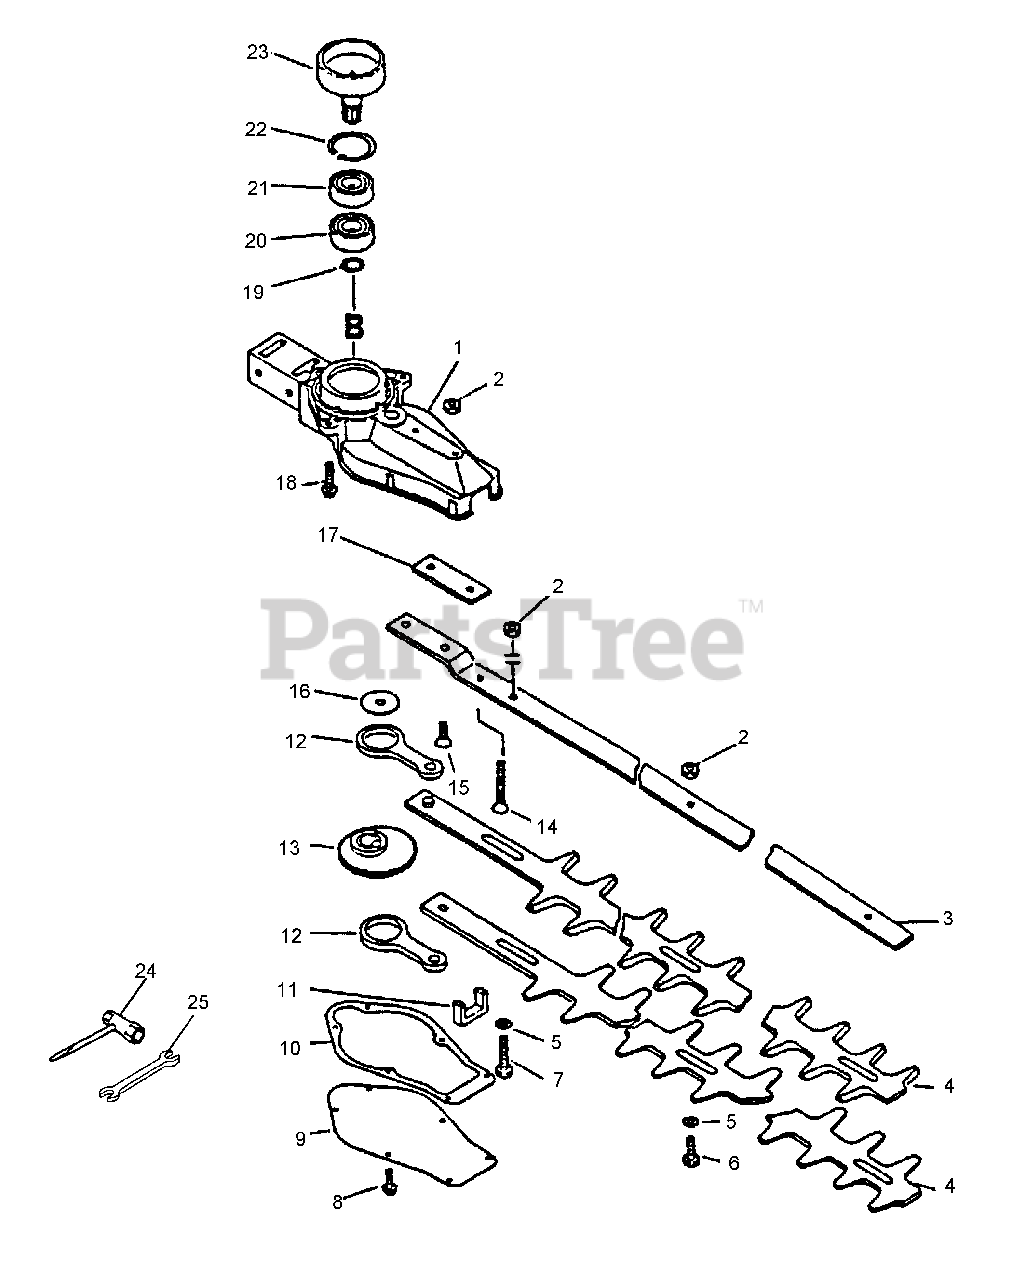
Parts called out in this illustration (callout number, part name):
1	CASE, GEAR
3	BAR, 20" FRAME
4	BLADE - 20"
5	WASHER 6.5×15.5×0.6
6	BOLT, CUTTER
7	BOLT 6×35
8	BOLT 4×10
9	COVER, GEAR CASE
10	GASKET, GEAR CASE
12	ROD, CONNECTING
14	SCREW 5×30
15	SCREW 6×25
17	PLATE, EYE
18	BOLT 5×20
19	RING, SNAP 14
20	BEARING, BALL 6202
21	BEARING, BALL 6202
22	RING, SNAP 35
23	DRUM, CLUTCH
24	T-WRENCH 13×19×180
25	SPANNER 8×10
